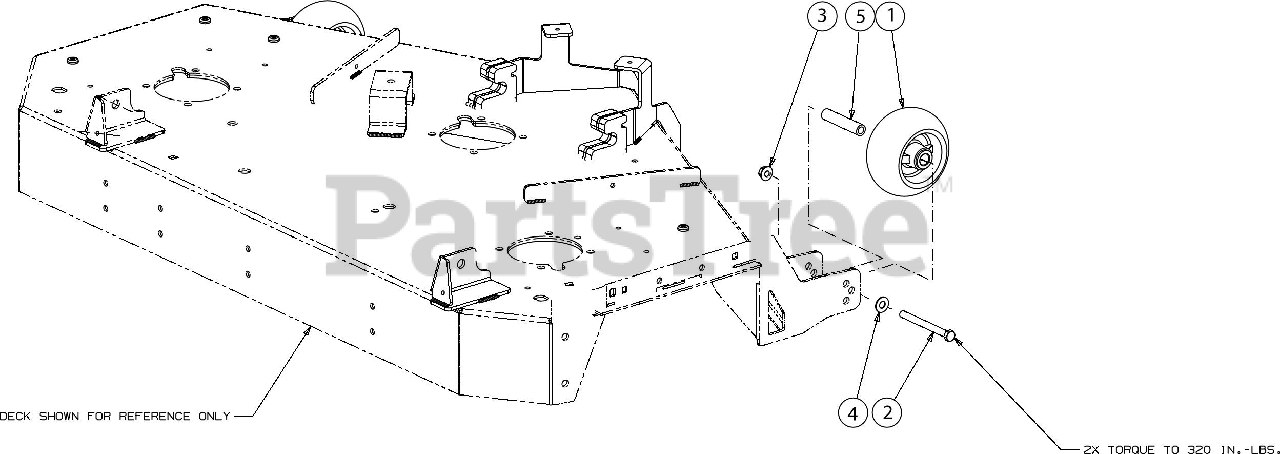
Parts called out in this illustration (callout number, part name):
1	WHEEL ASSEMBLY 5"
2	HEX SCREW 3/8-16 x 4.00
4	FLAT WASHER
5	WHEEL SPACER .38ID x 3.04LG
